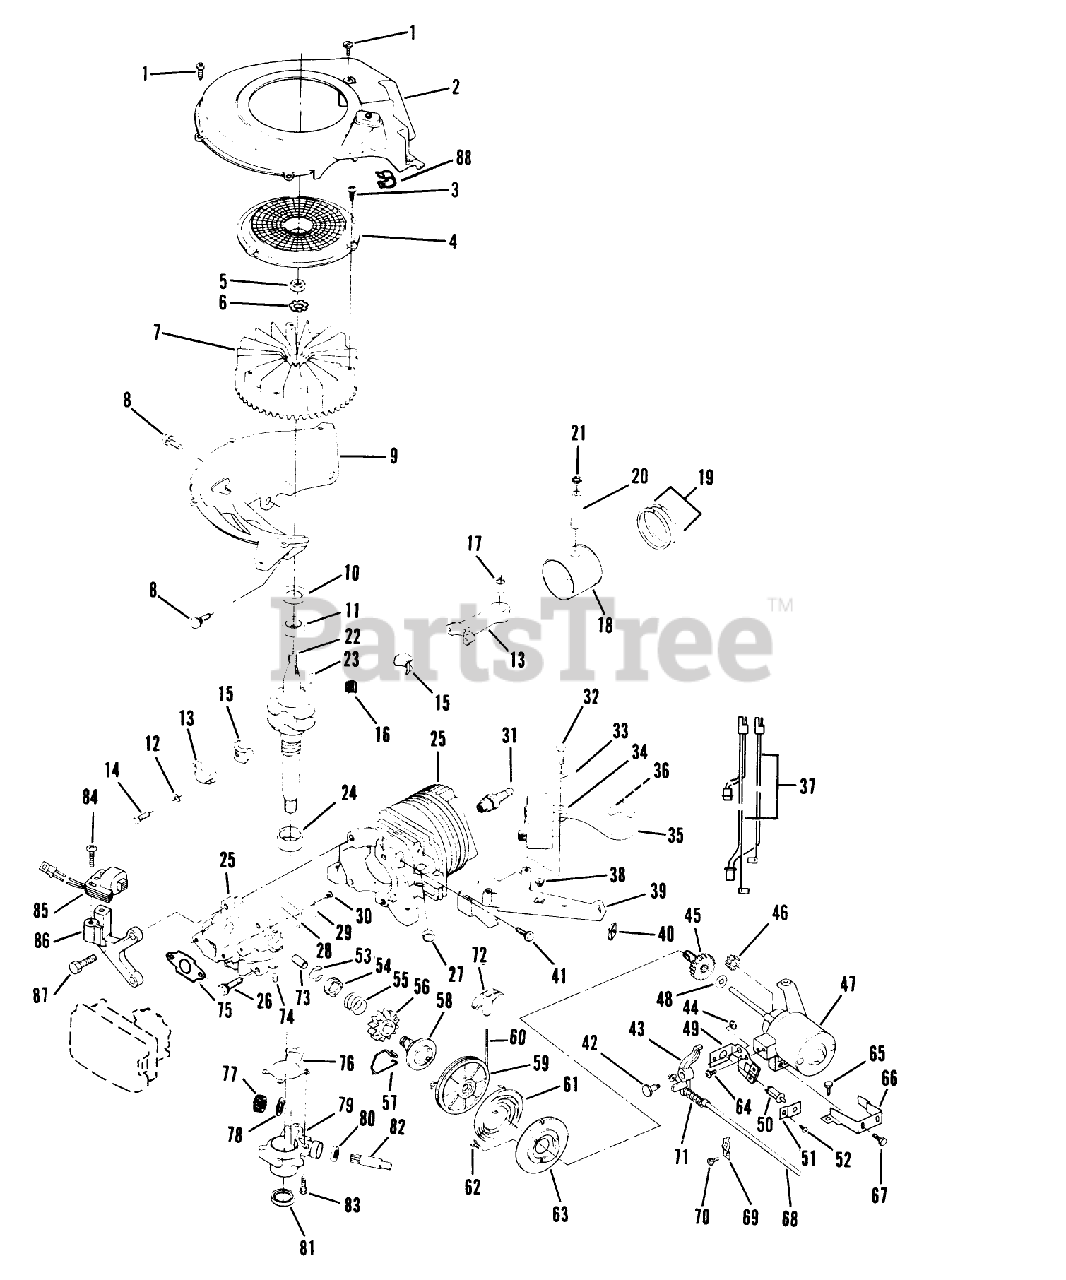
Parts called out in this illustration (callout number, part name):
1	SCREW S
2	AIR BAF&EYELET S
3	SCREW F
5	NUT
8	SCREW-SEMS
11	BEARING V
14	SCREW
15	LINER ASM
17	BEARING AY F
21	RING-RETAINING
23	KEY
24	BEARING S
26	SCREW S
27	PLUG-CORE VF
29	PLATE-BACKUP, REED
33	TERMINAL S
35	HT LEAD&COVER XEV
38	NUT-CLIP
40	NUT - SPEED S
42	PIN INTERLOCK
46	PINION
53	RET.RING EF
55	*SPRING PINION EF
56	PINION EF
57	SPRING F
58	CLUTCH AY S
59	PULLEY & CLUTCH BEARING
61	SPRING S
62	SCREW EF
64	SCREW
67	SCREW
69	CLIP S
72	HANDLE STARTER S
73	SLEEVE F
74	SET SCREW
75	GASKET CARB S
76	GASKET S
77	GEAR, DR SHAFT S
78	THRUST WASHER
80	SEAL S
88	Clamp-Wire Harness
